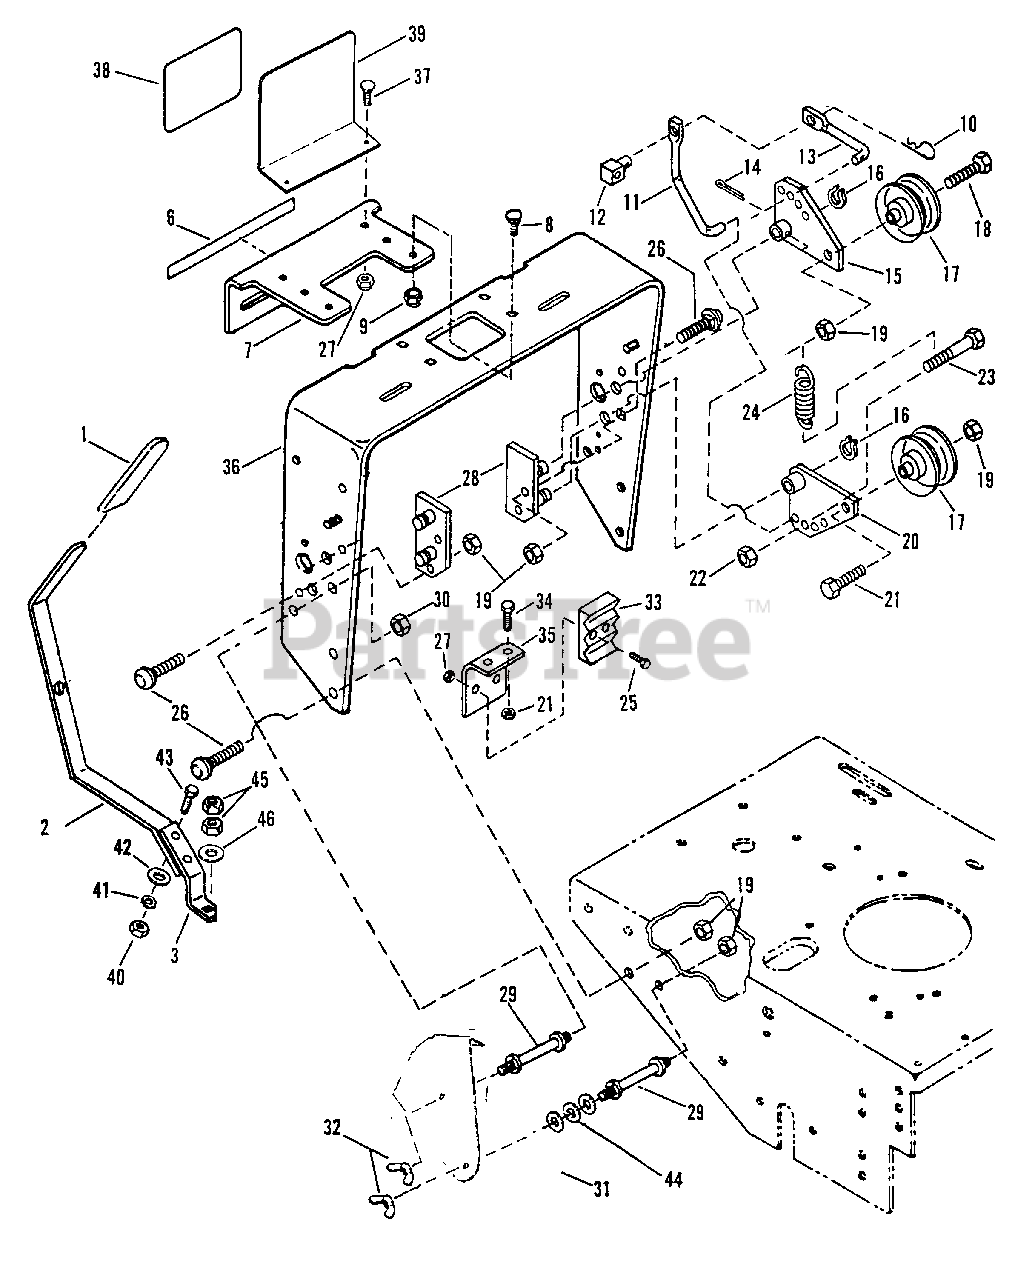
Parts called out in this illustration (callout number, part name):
1	GRIP, Shift Lever
2	LEVER, Upper Shifter
3	LEVER, Lower Shifter
6	DECAL, Shift
7	QUADRANT, Shift
8	BOLT, 1/4-20 x 3/4" Short Neck Carriage, Grade 5
9	NUT, 1/4-20 Hex, Nyloc
10	HAIR-PIN, 3/32 x 1-3/16"
11	LINK, Long (Left Hand)
12	SWIVEL
13	LINK, Short
14	COTTER-PIN, 3/32 x 1"
15	WELDMENT, Idler (Upper Left & Lower Right Sides)
16	RING, 5/8" External Retaining
17	PULLEY, Idler
18	BOLT, 3/8-16 X 2, GD5, CZ
19	NUT, 3/8-16, HEX TOP LOCK
20	WELDMENT, Idler (Lower Left & Upper Right Sides)
21	NUT, 5/16-18 HEX NYLON LOCK
22	NUT, 5/16-18 Hex Flange Lock, Grade 5
23	BOLT, 5/16-18 X 3/4 GD5
24	SPRING, Extension
25	BOLT, 1/4-20 X 1" GD5 CZ
26	BOLT, 3/8-16 x 1" Carriage, Grade 2
27	NUT, 1/4-20 HEX NYLON LOCK
28	WELDMENT, Idler Pivot (Left Hand)
29	STUD, Fender Mount
30	NUT, 3/8-16 Hex Jam
31	FENDER
32	WING-NUT, 3/8-16
33	REGULATOR/RECTIFIER
34	SCREW, 5/16-18 x 3/4"
35	BRACKET,
36	BRACKET, Tank
37	SCREW, 1/4-20 x 3/4" Hex Head Cap, Grade 5
38	DECAL, Caution
39	PLATE, Caution Decal
40	NUT, 5/16-18 HEX
41	WASHER,Slit Lock 5/16"
42	WASHER, Flat, 11/32"
43	BOLT, 5/16-18 X 1-1/4 GD5 YZ
44	WASHER, 1/4 Flat
45	NUT, 3/8-24 HEX
46	WASHER, 3/8 Heavy
